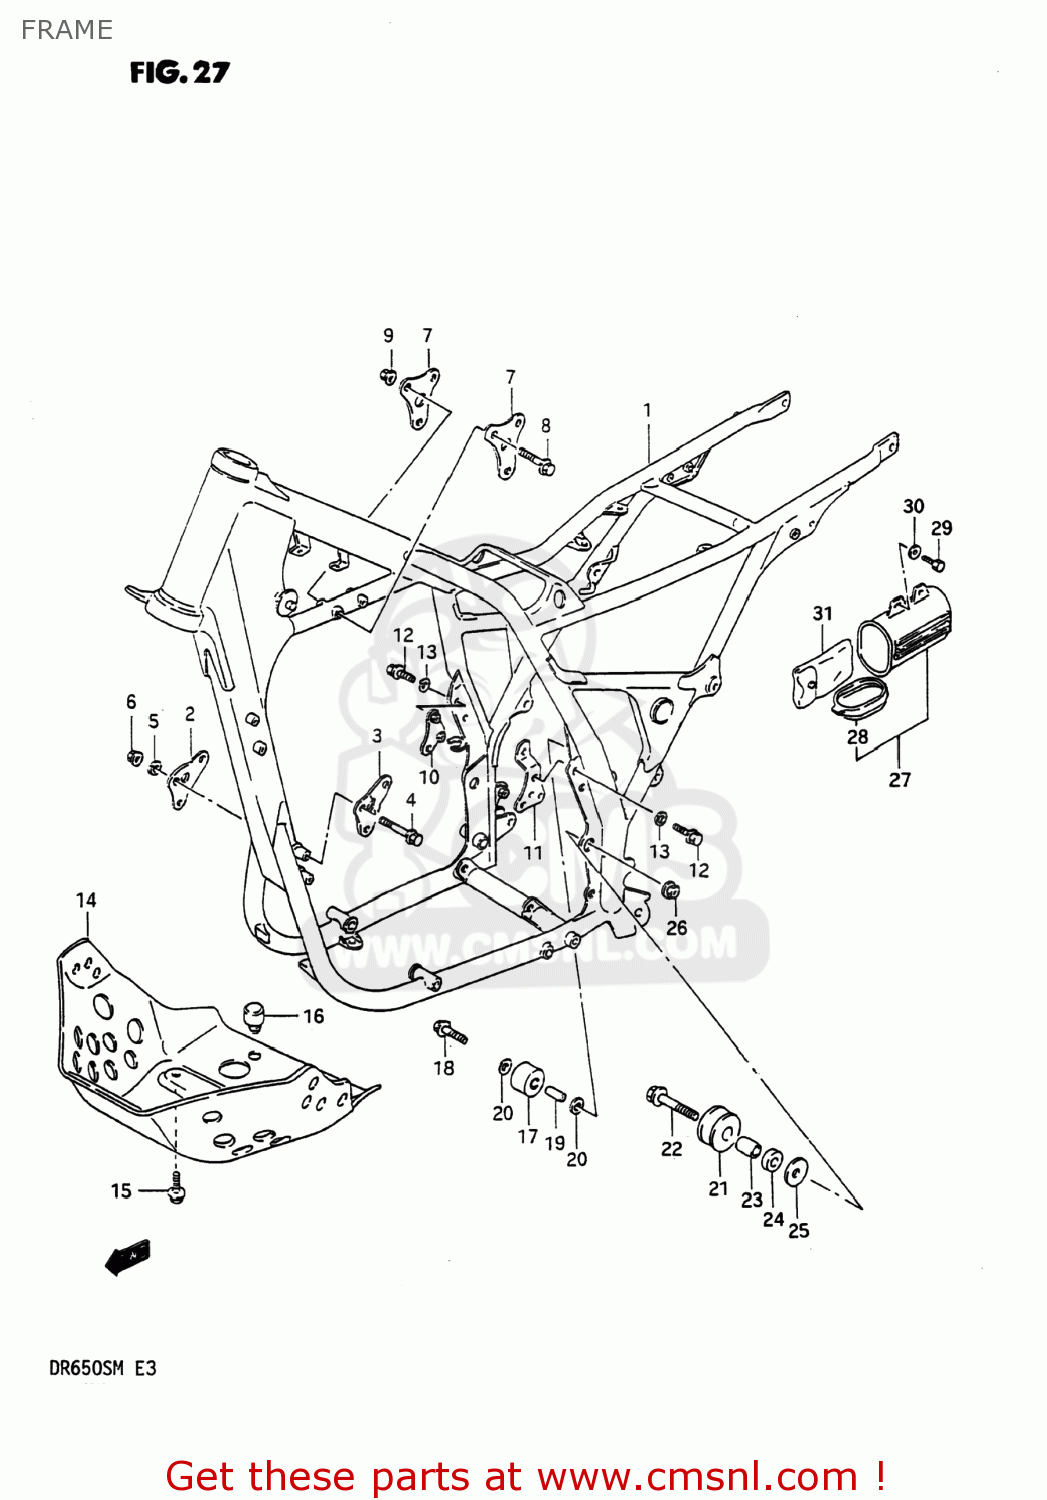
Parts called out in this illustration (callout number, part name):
1	FRAME
2	PLATE,ENGINE MOUNTING
3	PLATE,ENGINE MOUNTING
4	BOLT(8X72)
5	WASHER,LOCK
6	NUT
7	PLATE,ENGINE MOUNTING
8	BOLT(8X50)
9	NUT
10	PLATE,ENGINE MOUNTING
11	PLATE,ENGINE MOUNTING
12	BOLT(8X20)
13	WASHER,LOCK
14	PROTECTOR,ENGINE
15	BOLT 8X16
16	CUSHION
17	ROLLER,CHAIN CONTROL
18	BOLT(8X41)
19	SPACER (8.6X13.8X28)
20	WASHER (8.2X24X1.6)
21	ROLLER,CHAIN CONTROL
22	BOLT 8X50
23	SPACER(8.6X12X25.5)
24	SPACER,LOWER
25	WASHER
26	NUT
27	HOLDER,TOOL
28	CAP,HOLDER
29	BOLT M6X16
30	WASHER (6.5X18X1.6)
31	TOOL SET
